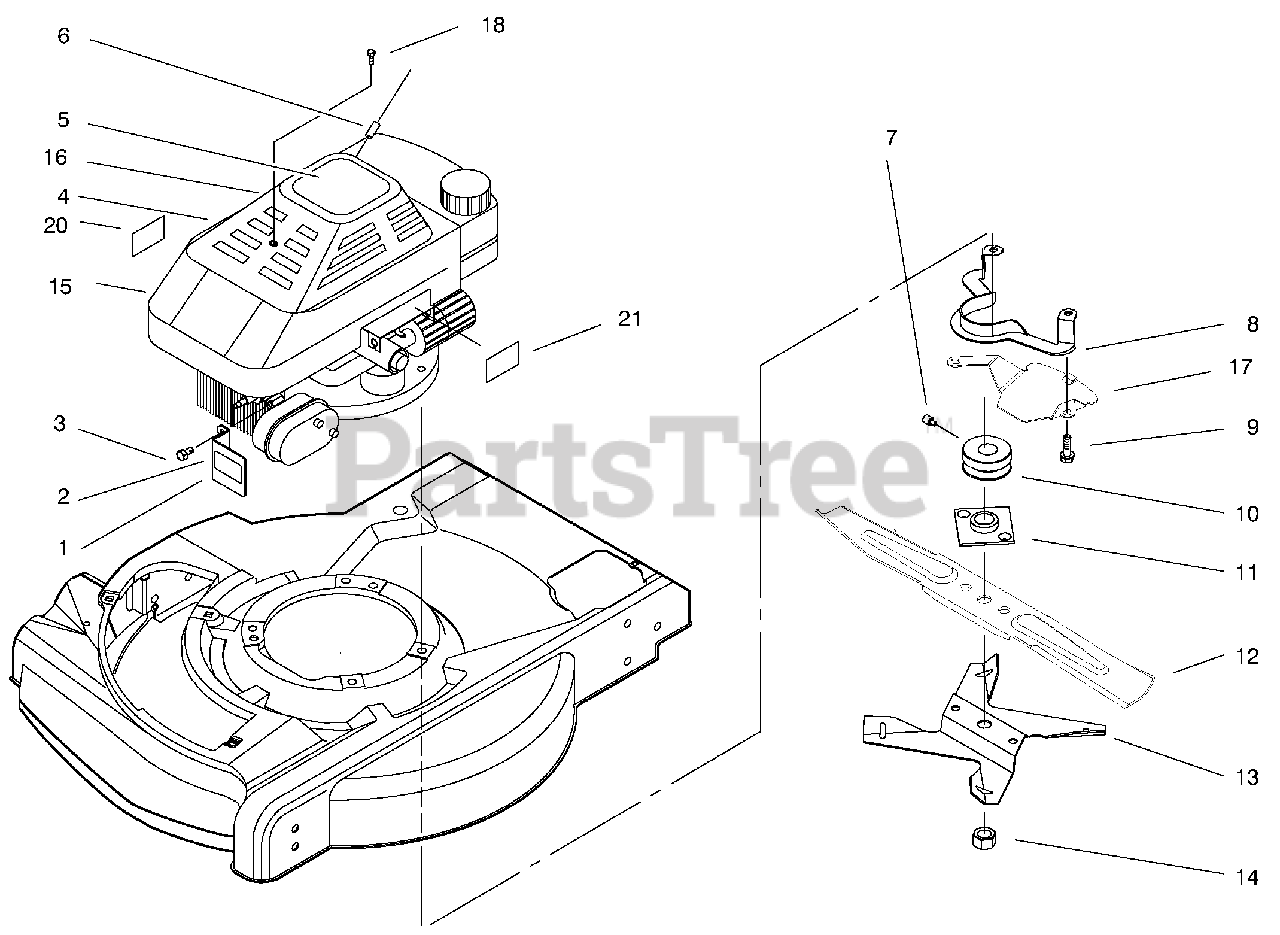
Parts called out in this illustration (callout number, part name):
1	Guard-Muffler (Incl. Ref.#2)
2	Decal-Warning
4	Engine-4 Cycle
5	Decal-Shroud (Model No. 10202 Only)
6	Stop-Rope
7	Screw-Set (Model No. 10302 Only)
8	Guide-Belt (Model No. 10302 Only)
9	Screw-Engine Mount
10	Pulley-Engine (Model No. 10302 Only)
11	Plate & Collar Ass'y
12	Blade-21"
13	Fan-Mulching
14	Nut-Blade
15	Shroud-Engine
16	Cover-Recoil
17	Shield-Grass (Model No. 10302 Only)
20	Decal-Oil (Model No. 10302 Only)
21	Decal-Primer
